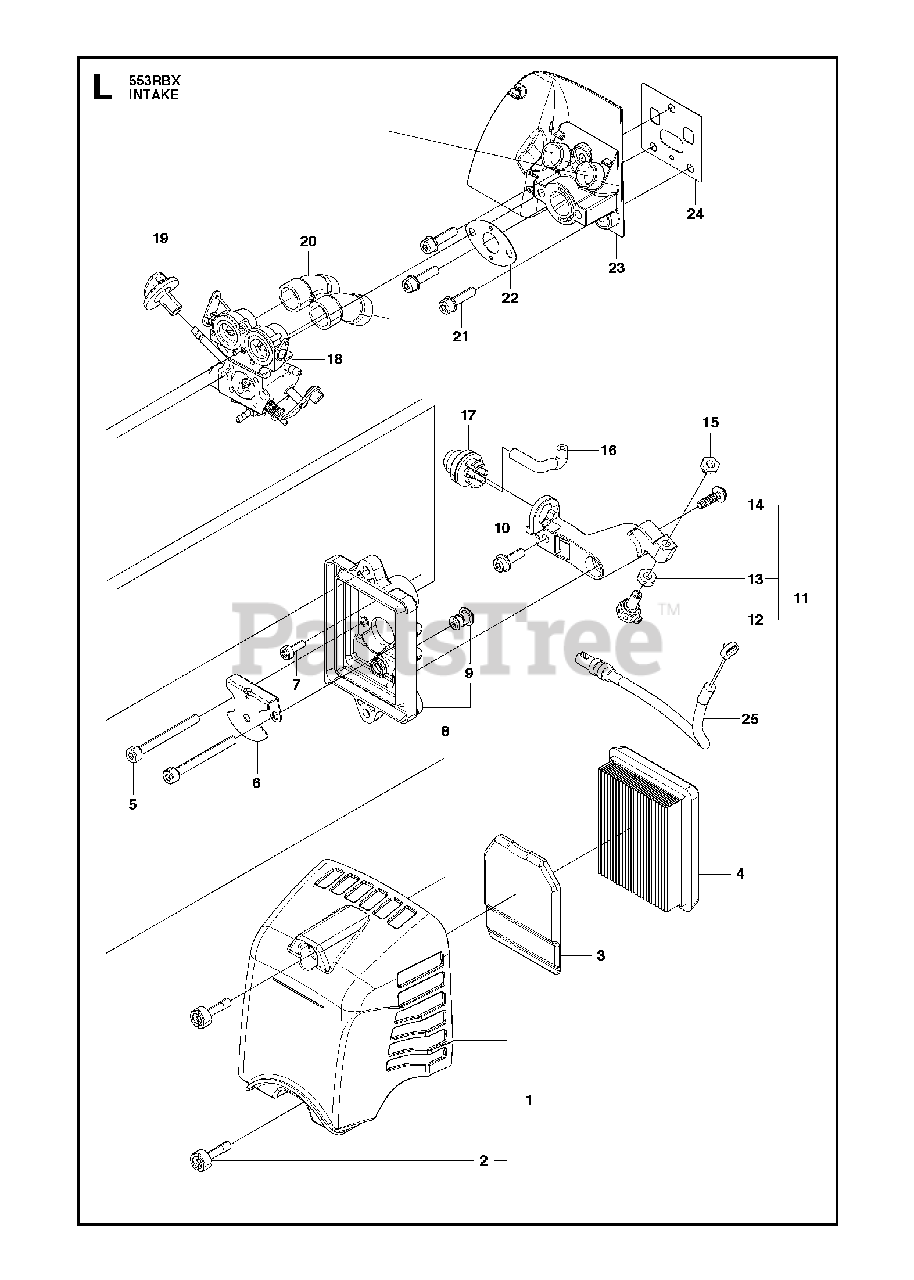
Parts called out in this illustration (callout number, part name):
2	SCREW
5	BOLT TORX M5XL50 T27
7	BOLT M4 X 12 T27
9	GROMMET
10	BOLT
11	BRACKET ASSY
12	SCREW CABLE ADJUST
13	NUT,CABLE ADJ(RPLS175181180
14	SCREW
15	STOPPER
21	BOLT, TORX
